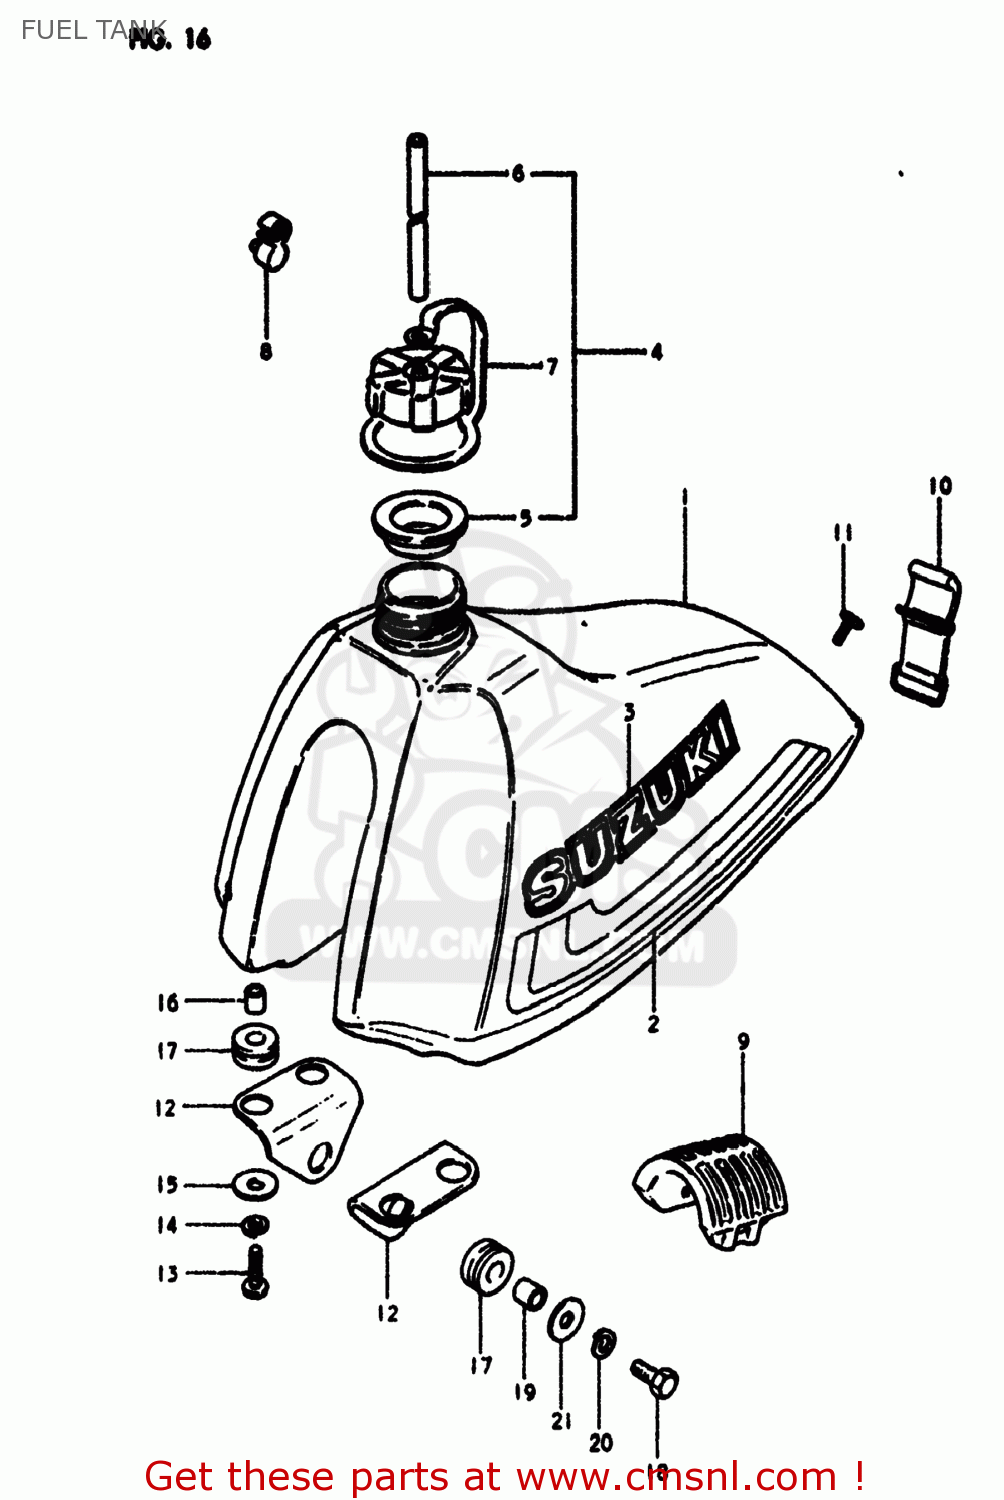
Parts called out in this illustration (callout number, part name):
1	TANK ASSEMBLY,FUEL
2	TAPE SET,FUEL TANK
3	EMBLEM
4	CAP SET,FUEL TANK
5	GASKET,FUEL TANK CAP (NAS)
6	HOSE
7	BAND,FUEL TANK CAP
8	CLAMP,BREATHER HOSE
9	CUSHION,FUEL TANK
10	BAND
11	SCREW(6X18)
12	BRACKET,FUEL TANK,LOWER
13	SCREW
14	LOCK WASHER
15	WASHER (6.5X24X1.6)
16	SPACER(6.8X12X11)
17	CUSHION
18	BOLT
19	SPACER (8.8X12X11)
20	LOCK WASHER
21	WASHER (8.2X24X1.6)
